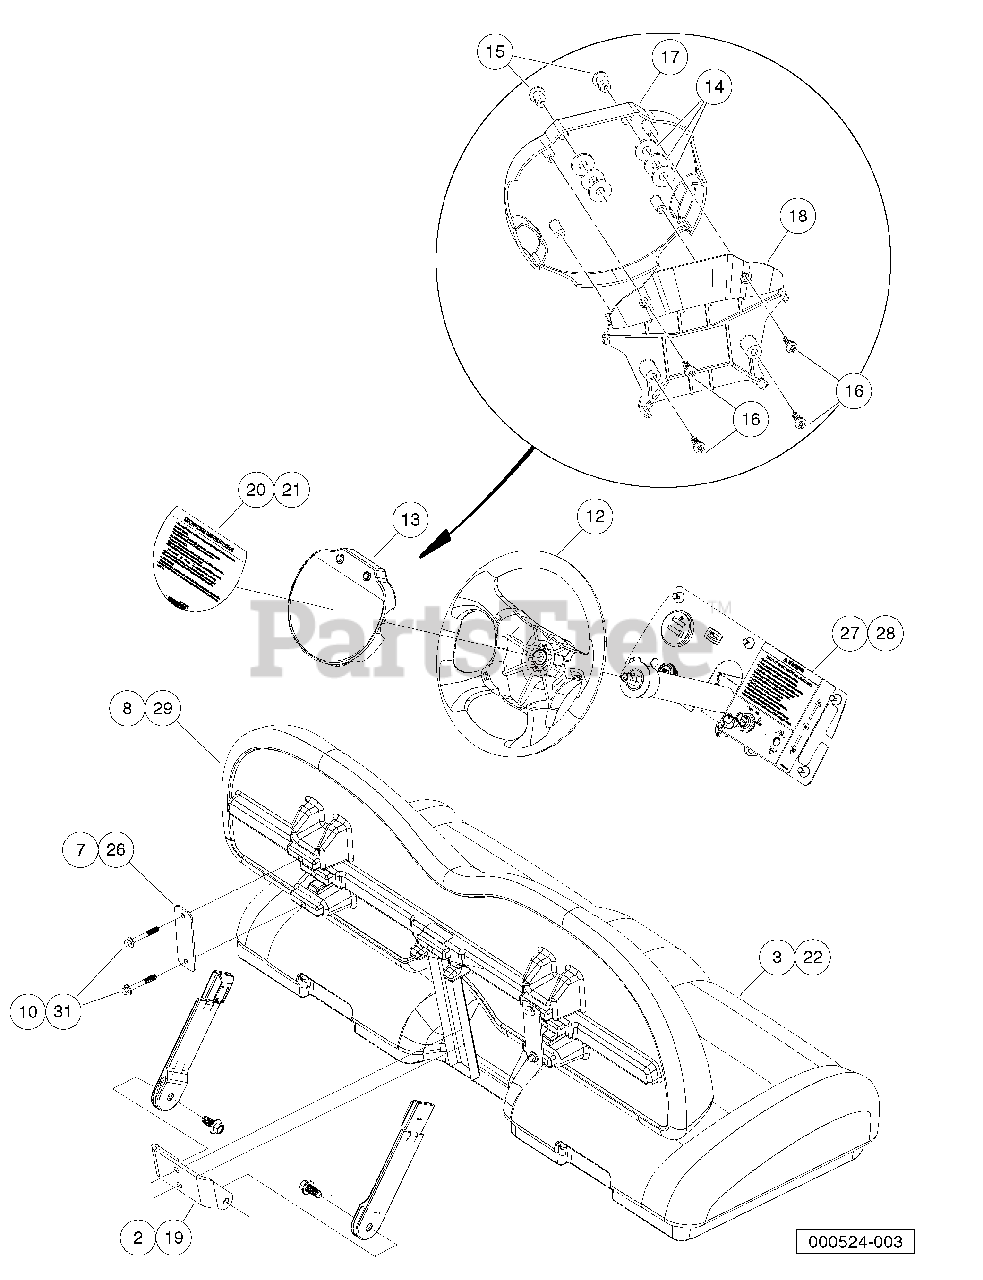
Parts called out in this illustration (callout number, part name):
1	Kit, Bench Seat, Seat Only
2	Bracket, Seat Belt, Bench
3	Asm, Seat Bottom, Bench, Gray
4	Hinge Plate
5	Asm, Seat Bottom, Bench
6	Bolt Flg Blk, M8 X 25, Loctite
7	Bracket, Seat Back, AWD
8	Seat Back, Bench, Gray
9	Instructions, Bench Seat
10	Bolt Flg Blk, M8 X 55, Loctite
11	Kit, Bench Seat, Complete
12	Steering Wheel, Comfort Grip, Hex
13	Center, Plate, Steering Wheel
14	Washer, 5/16 Flat
15	Blind Rivet, Push Type
16	Screw, Torx Pan Hd Pt, M6 X 20
17	Scorecard Plate, Comfort Grip
18	Scorecard Back Plate
19	Bracket, Seat Belt, Bench
20	Decal, Oper Instr, Awd Se Dsl
21	Decal, Oper Instr, Awd Se Gas
22	Asm, Seat Bottom, Bench, Gray
23	Hinge Plate
24	Asm, Seat Bottom, Bench
25	Bolt Flg Blk, M8 X 25, Loctite
26	Bracket, Seat Back, AWD
27	Decal, Warning, Iinstrument Panel, AWD Gas
28	Decal, Warning, Iinstrument Panel, AWD Diesel
29	Seat Back, Bench, Gray
30	Instructions, Bench Seat
31	Bolt Flg Blk, M8 X 55, Loctite
